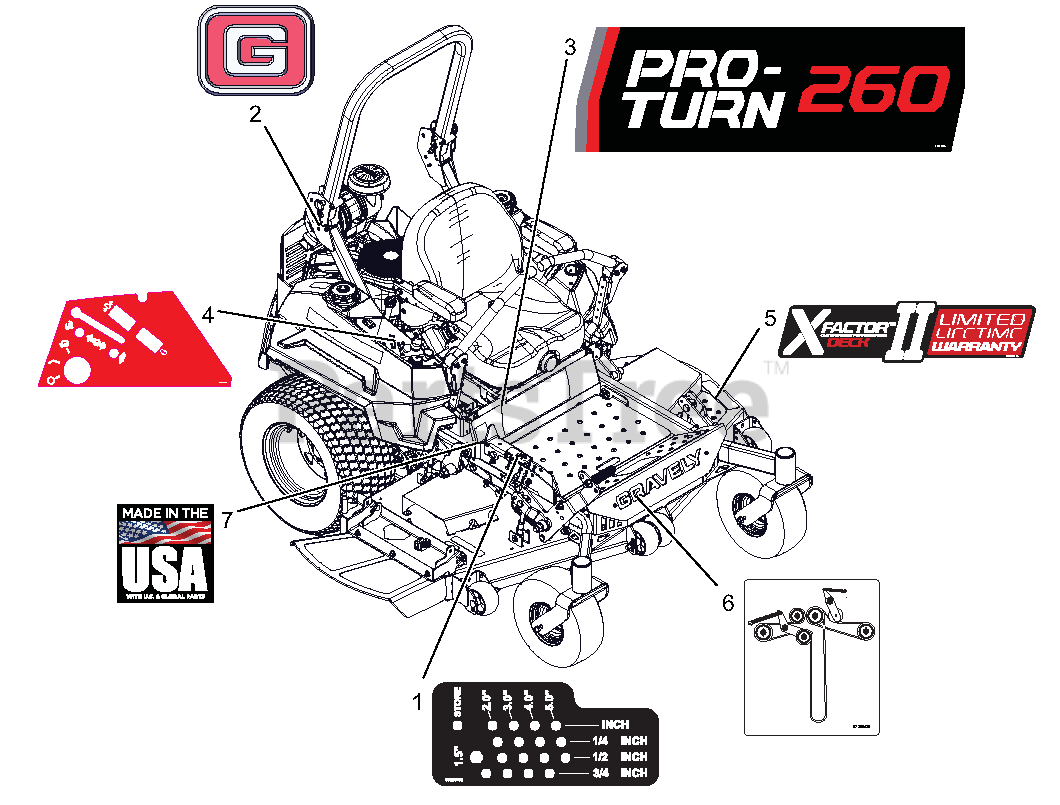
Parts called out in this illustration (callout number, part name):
1	DECAL, HEIGHT OF CUT
2	DECAL, GRAVELY BRAND
3	DECAL, PRO-TURN 260
4	DECAL, EFI CONTROL PANEL
5	DECAL, X-FACTOR DECK
6	DCL,BELT ROUTE-RH BK-SIDE IDLR
7	DECAL, MADE IN USA
